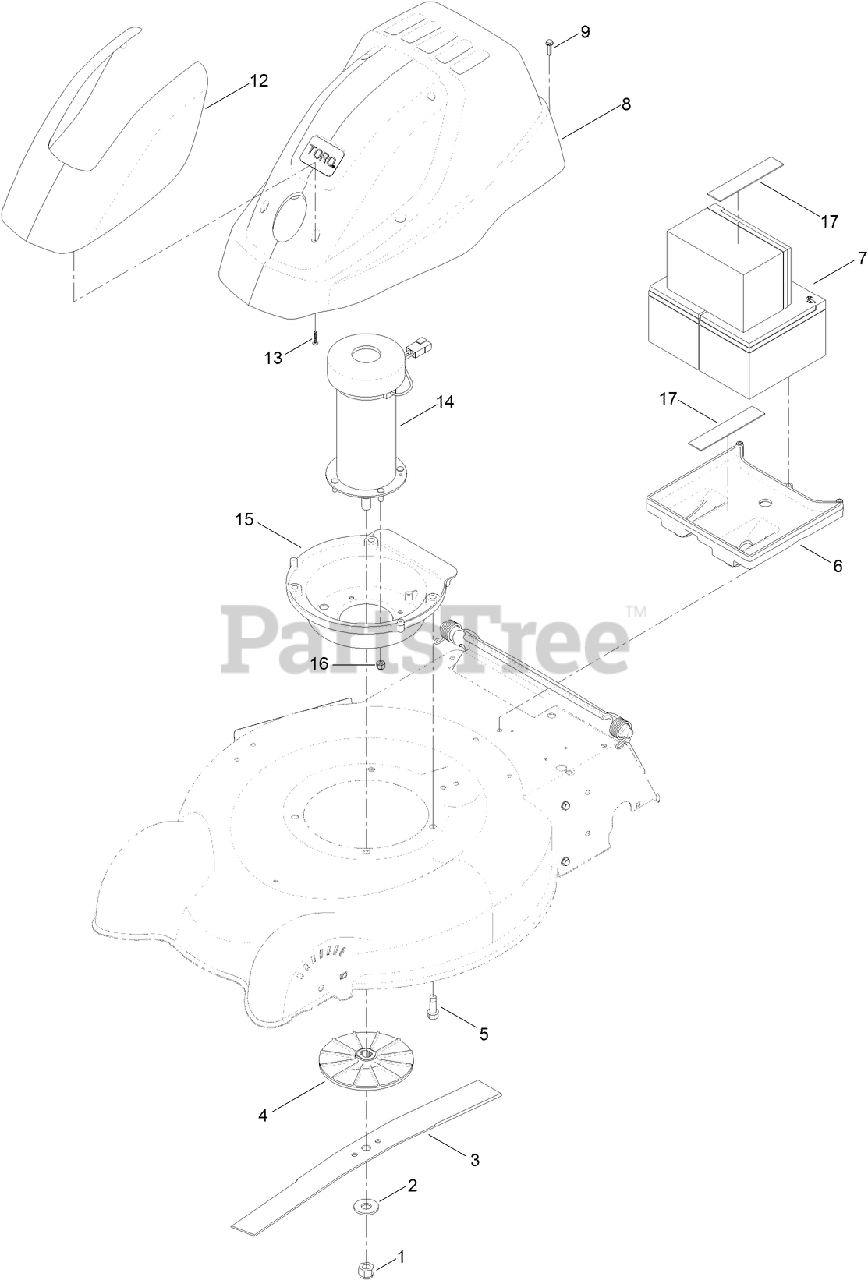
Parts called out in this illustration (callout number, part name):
1	NUT-HEX
2	WASHER-FLAT
3	BLADE-20 INCH
4	FAN MOTOR ASM
5	SCREW-TAPTITE
6	TRAY-BATTERY
7	BATTERY ASM
8	SHROUD ASM
9	SCREW-HWH
12	COVER-SHROUD
13	SCREW-PPH
14	MOTOR-36V
15	BASE-MOTOR
16	NUT-LOCK, NI
17	TAPE-FOAM, 2 SIDED
